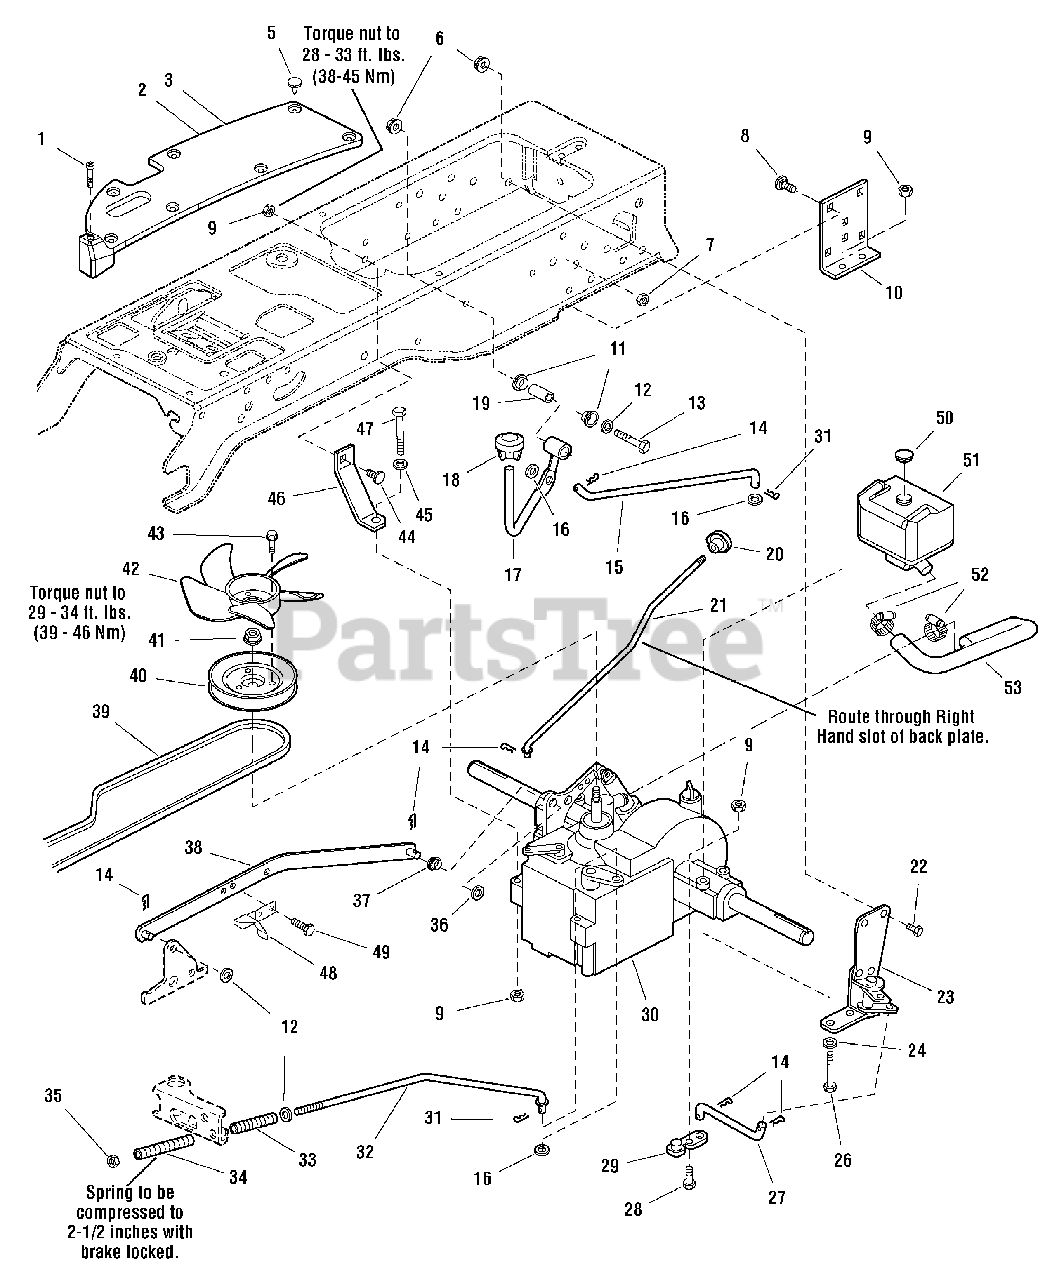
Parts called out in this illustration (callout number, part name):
1	SCREW, Pan Head Torx Taptite, 1/4-20 x 1-1/4
2	PAD, Footrest, LH, Differential Lock
3	PAD, Footrest, RH
5	FASTENER, 11/16" Long, Stem Plastic
6	NUT, Hex Flange Whiz Lock, 3/8-16, Large
7	NUT, Hex KEPS, 3/8-16
8	CARRIAGE BOLT, 3/8-16 x 1
9	NUT, Hex Flagne ESNA, 5/16-18
10	SUPPORT
11	BUSHING, 5/8 x 3/4 x 13/32, Powder Metal
12	WASHER, 3/8
13	CAPSCREW, Hex Head, 3/8-16 x 2-1/4
14	PIN, Quick
15	ROD, Differential Lock, 15-3/16 Long
16	WASHER, 7/16
17	ROD & TUBE ASSEMBLY, Differential Lock Pedal
18	KNOB
19	SPACER, 25/64 x 5/8 x 1-1/2, Hardened
20	KNOB, 3 Sided Soft
21	ROD, Free Wheel, 18-3/16 Long
22	CAPSCREW, Hex Head, 3/8-16 x 1, Black
23	PIVOT ASSEMBLY, Differential Lock
24	WASHER, 5/16, Black
26	CAPSCREW, Hex Head, 5/16-18 x 3
27	ROD, Differential Latch, 2 Bends, 6-3/16 Long
28	CAPSCREW, Hex Head, 5/16-18 x 1
29	ARM, Differential Lock
30	TRANSMISSION ASSEMBLY, K66L Transmission
30	TRANSMISSION ASSEMBLY, K66AC Transmission
31	PIN, Cotter, 3/4, Black
32	ROD, Brake, 17-27/64 Long
33	SPRING, Compression
34	SPRING, Compression
35	NUT, Hex Flange ESNA, 3/8-16
36	WASHER, Flat, 1/2
37	BEARING, Nyliner
38	ARM & WELD PINS ASSEMBLY, Control K66
39	V-BELT
40	PULLEY & HUB ASSEMBLY, Transmission
41	NUT, Hex Flange, M10-1.5, Nylon Insert
42	FAN, 5 Blades, 3 Holes
43	CAPSCREW, Hex Washer Head Taptite, 1/4-20 x 1-1/8
44	CARRIAGE BOLT, 5/16-18 x 1
45	WASHER, 5/16
46	STRAP, 4-1/4 Long
47	CAPSCREW, Hex Head, 5/16-18 x 2-1/2
48	ACTUATOR, Switch
49	CAPSCREW, Hex Head Taptite, 5/16-18 x 1/2
50	CAP, Expansion Tank Plastic
51	TANK, Oil Natural
52	CLAMP, Hose Worm Drive #20 1-3/4"
53	HOSE, Expansion Tank Formed
